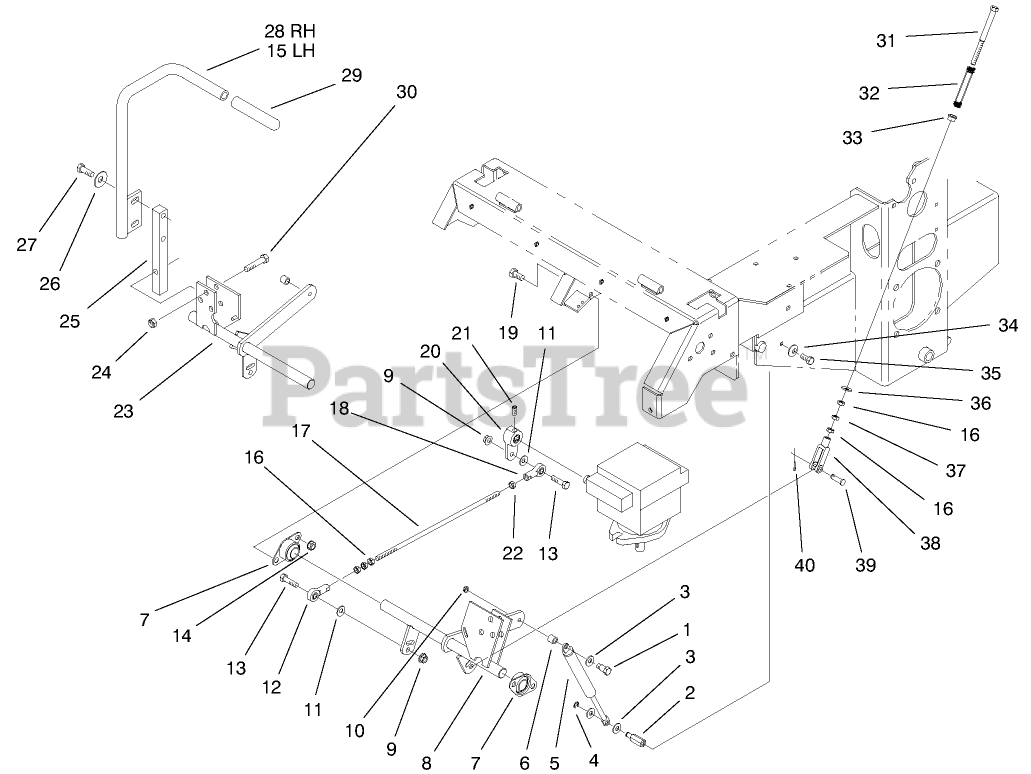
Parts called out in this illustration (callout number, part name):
1	Screw-HSH
2	Pin-Damper Anchor
3	WASHER-PLAIN
4	E-Ring
5	Damper
6	Spacer
7	Bearing-Side Flange
8	Bracket-Motion Control, LH
9	NUT-HF
10	NUT-HF
11	WASHER-FLAT
12	Ball Joint
13	SCREW-HH
14	NUT-HHF, WHIZ
15	Lever-LH
16	NUT-HEX
17	Link-Pump Control
18	Ball Joint LH
19	SCREW-HH
20	Arm-Pump Control
21	Screw
22	Nut
23	Bracket-Motion Control, RH
24	NUT-LOCK, NI
25	Arm
26	Washer
27	SCREW-HH
28	Lever-RH
29	Grip
30	SCREW-HH
31	Bolt
32	Spring
33	Bushing
34	Washer-Lock
35	SCREW-HH
36	WASHER-FLAT
37	NUT-JAM
38	Yoke
39	Pin-Clevis
40	PIN-COTTER
